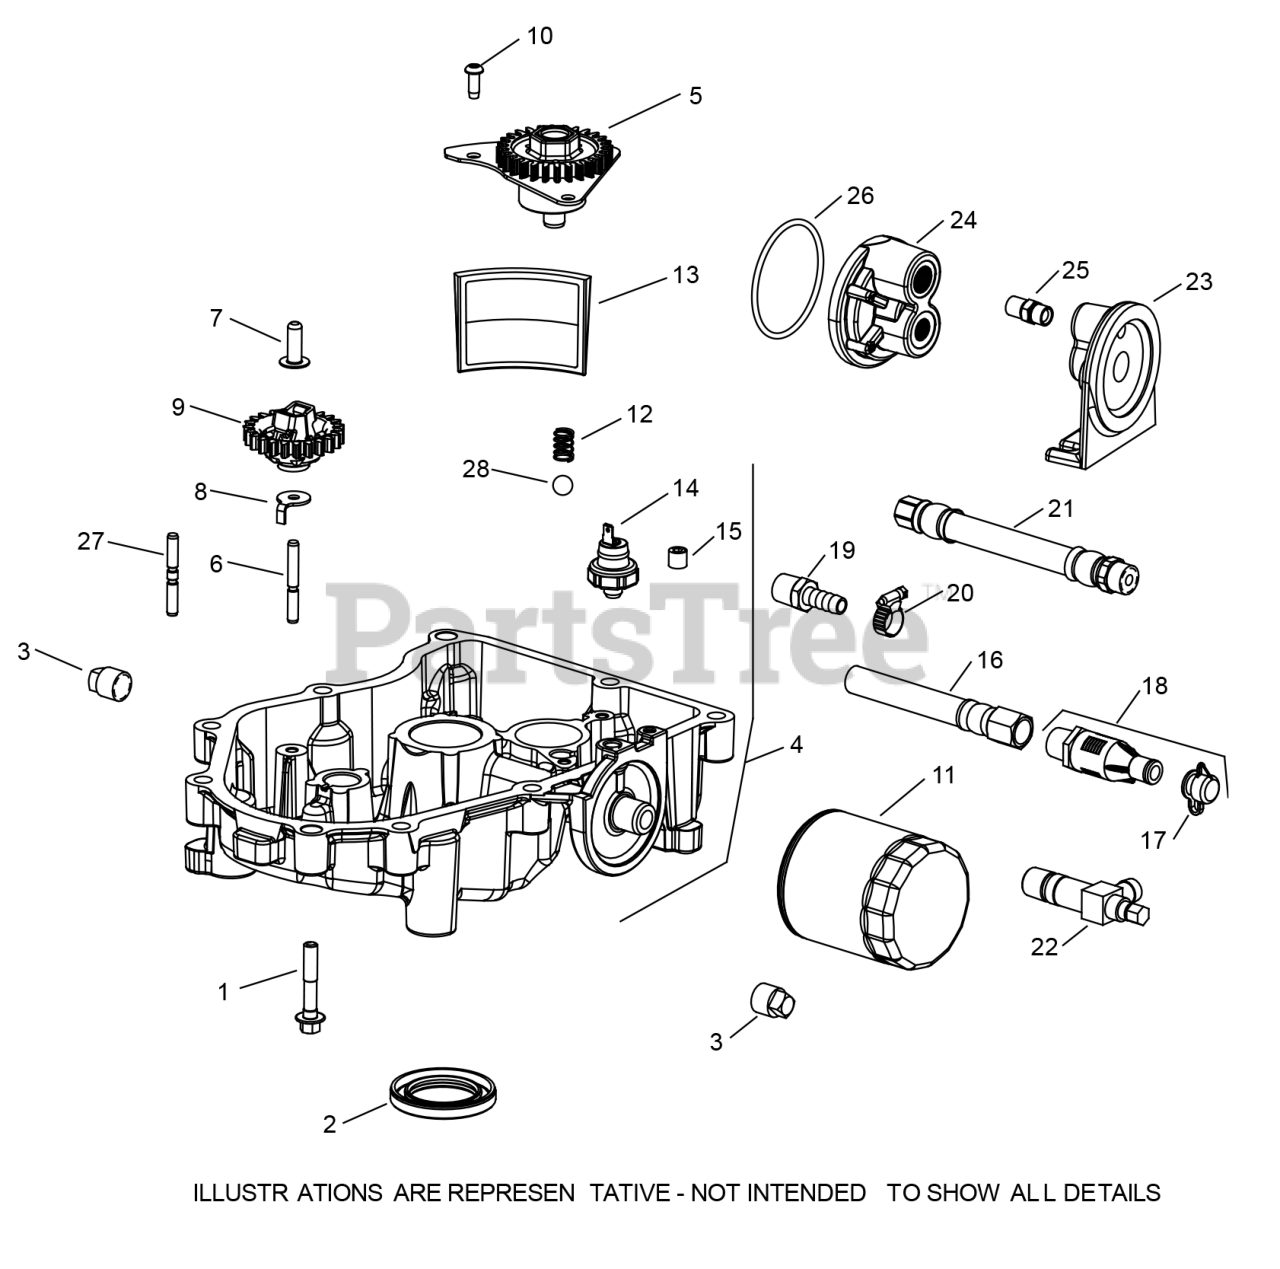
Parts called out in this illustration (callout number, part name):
3	PLUG-HEX HEAD PIPE
4	OIL PAN ASSEMBLY
5	OIL PUMP ASSEMBLY
6	GOVERNOR SHAFT GEA
7	PIN-GOV REGULATING
9	GEAR KIT-GOVERNOR
10	SCREW-BUTTON HEAD
11	OIL FILTER-LONG
12	COMPRESSION SPRING
14	OIL PRESSURE SWITCH
